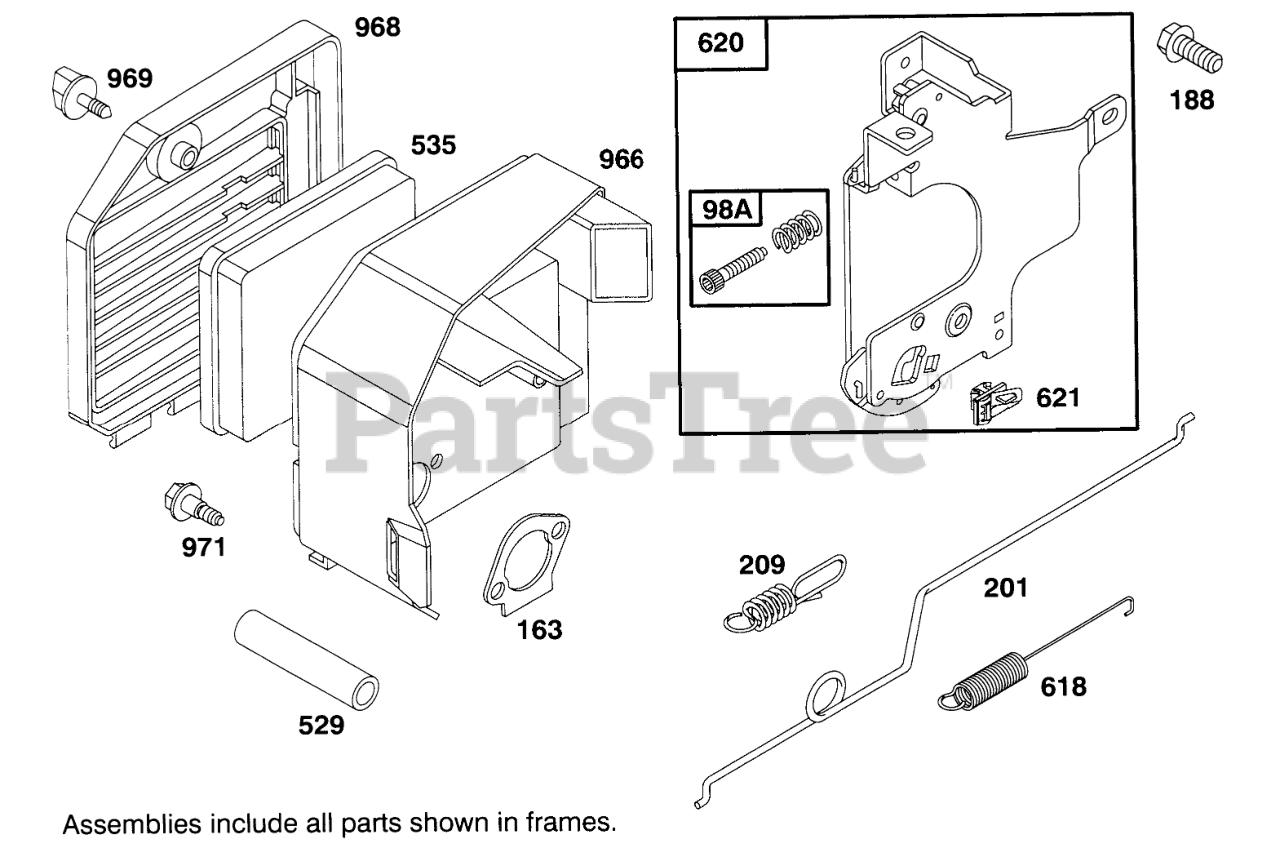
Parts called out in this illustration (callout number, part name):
98A	SPEED ADJUST. SCREW ASM
163	AIR CLEANER GASKET
188	Screw-Cap
201	GOVERNOR LINK
209	GOVERNOR SPRING
529	TUBE - BREATHER
535	FILTER ELEMENT
618	RETURN SPRING
620	CARBURETOR BRACKET
621	STOP SWITCH
966	AIR CLEANER BASE
968	AIR CLEANER COVER
969	AIR CLEANER SCREW
971	AIR CLEANER SCREW
